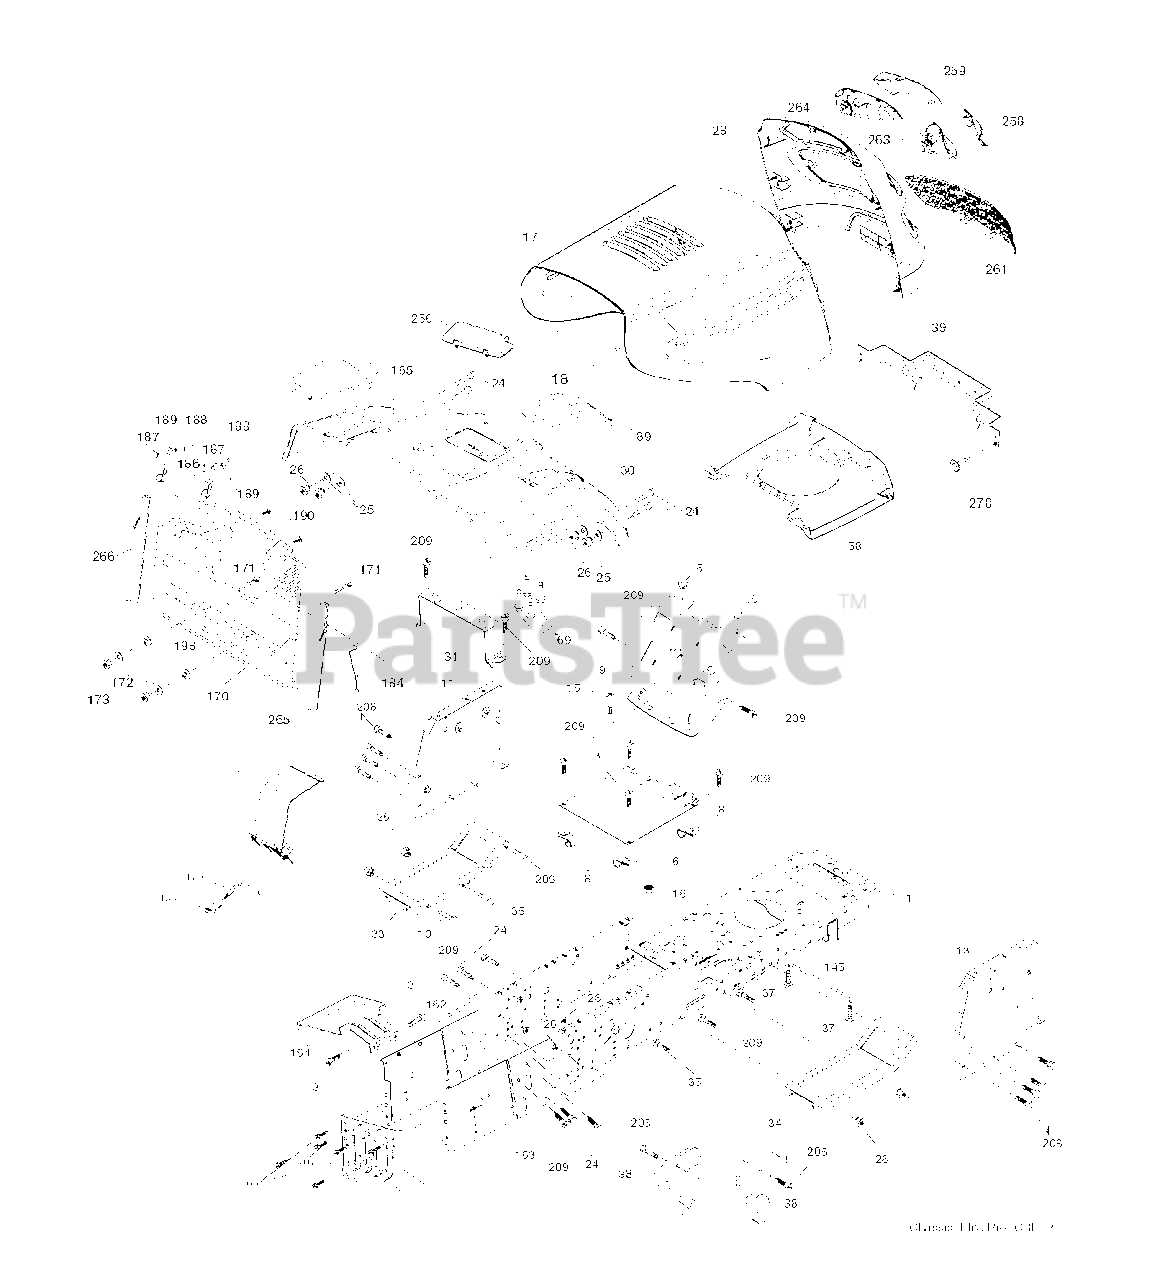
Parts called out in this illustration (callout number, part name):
1	CHASSIS
3	SCREW 3/8-16X3/4
5	BUMPER.RUBBER.HOOD
8	CLIP,INSULATOR
10	BOLT D
11	PANEL.DASH.LH.LTX
13	PANEL DASH RH
16	NUT
18	BUMPER.HOOD.LARGE.1.75"
25	WASHER
26	NUT
31	BRACKET SUPPORT FENDER
39	BRACKET PIVOT
69	SCREW.HI-LO.CONSOLE
145	ROD.PIVOT.HOOD
164	SUPPORT
171	BOLT
172	WASHER
186	LATCH ASSY
187	WELDNUT
189	LOCKWASHER
207	SCREW, 5/16-18 X 1/2
208	SCREW 3/8-16X1/2
209	SCREW, 3/8-16X3/4
263	BEZEL GRILL RH
264	BEZEL GRILL LH
278	SCREW
